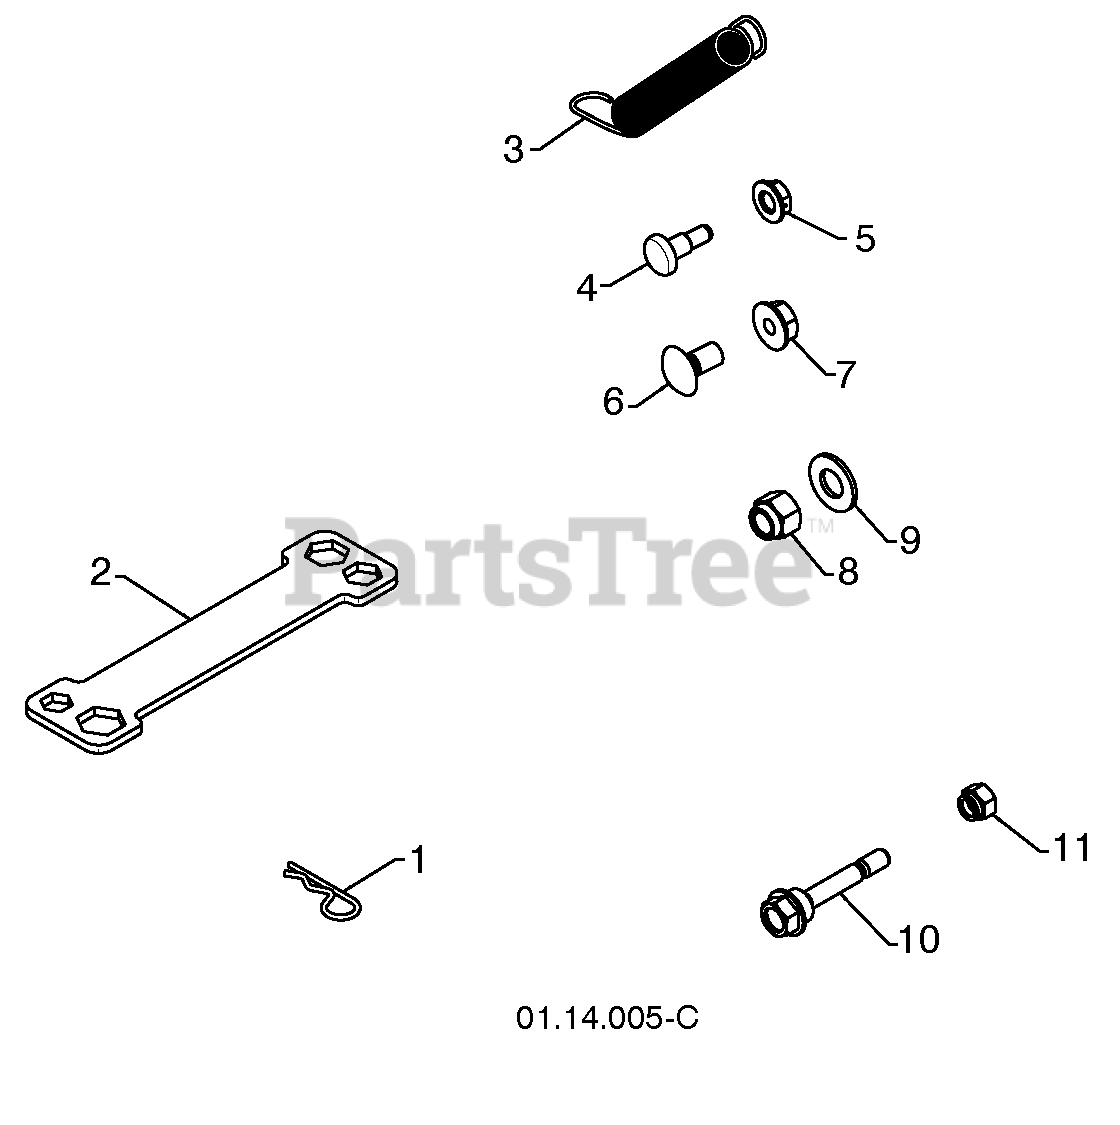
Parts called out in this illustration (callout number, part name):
1	RETAINER PIN
3	REMOTE SPRING
4	SHOULDER BOLT 1/4-20
5	LOCKNUT 1/4-20
6	CARRIAGE BOLT 5/16-18 X 5/8
7	LOCKNUT 5/16-18
8	LOCKNUT 3/8-16
9	WASHER 3/8
10	SHEAR BOLT 1/4-20 X 1-3/4
11	LOCKNUT 1/4-20
